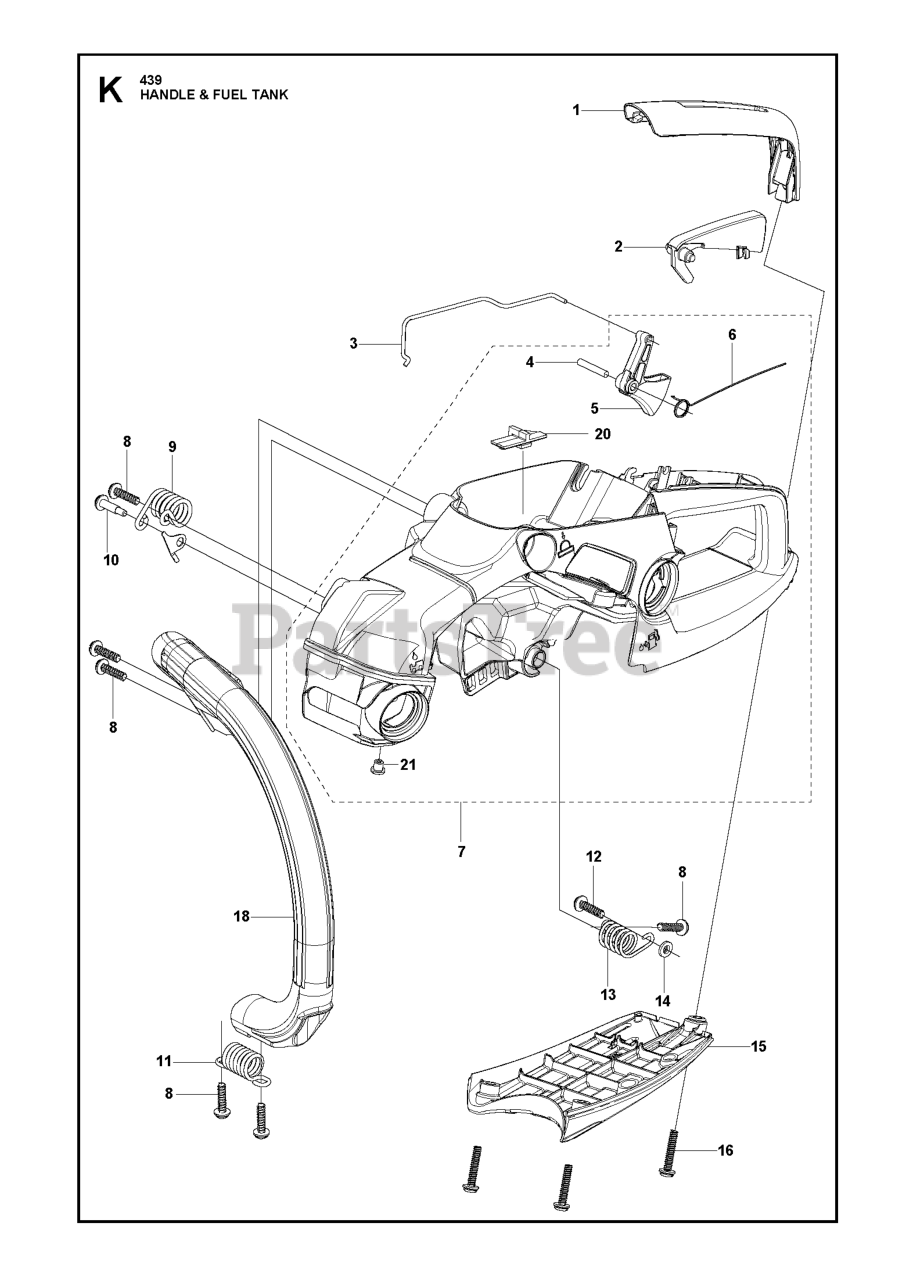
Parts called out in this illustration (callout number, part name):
1	COVER GRIP 439
3	THROTTLE ROD 436/GZ3500L
4	PIN 8488B42400
5	THROTTLE LEVER
6	SPRING
9	SPRING FRONT 439
11	SPRING FLYWHEEL SIDE
12	SCREW (RPLS 267132210)
13	SPRING, PTO
14	SPACER Z114283110
15	COVER HANDLE 439
18	FRONT HANDLE 439
20	GROMMET R HANDLE
